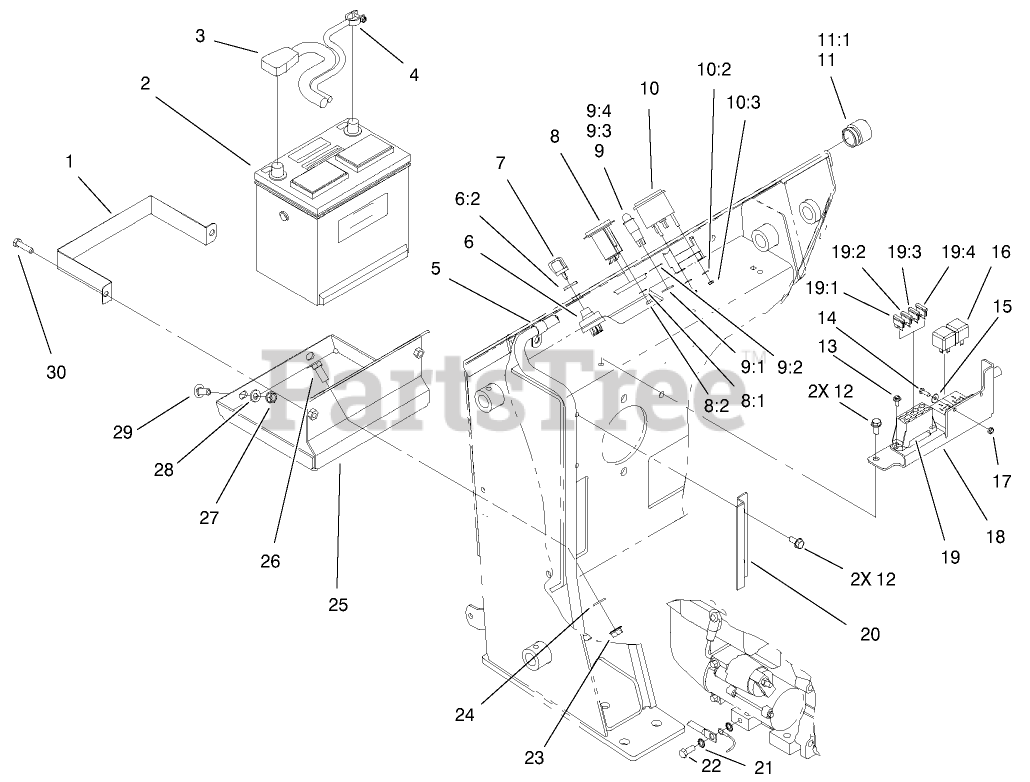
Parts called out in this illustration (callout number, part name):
1	BRACKET-CLAMP, BATTERY
2	BATTERY (DRY)
3	CABLE-BATTERY, POSITIVE
4	CABLE-BATTERY, NEGATIVE
5	CLAMP-R
6	Key Switch ASM
6:2	NUT-HH
7	KEY-IGNITION
8	GAUGE-HOURMETER
8:1	WASHER-LOCK
8:2	NUT-HEX
9	LIGHT-INDICATOR, RED
9:1	NUT-HEX
9:2	WASHER-LOCK
9:3	LED-MINIATURE
10	GAUGE-FUEL
10:2	WASHER-LOCK, INT
10:3	NUT-HEX
11	AUDIO ALARM ASM
11:1	NUT-PLASTIC, KNURLED
12	SCREW-HWHTF
13	SCREW
15	WASHER-PLAIN
16	RELAY
17	NUT-LOCK, NI
18	BRACKET-FUSE/RELAY
19	HARNESS-WIRE
20	SHIELD-WIRING
21	WASHER-LOCK
22	SCREW-HHF
23	NUT-HF
24	WASHER-FLAT
25	BATTERY TRAY ASM
26	SCREW-HH
27	NUT-LOCK, NI
28	WASHER-FLAT
29	SCREW-CARR
30	SCREW-HH
